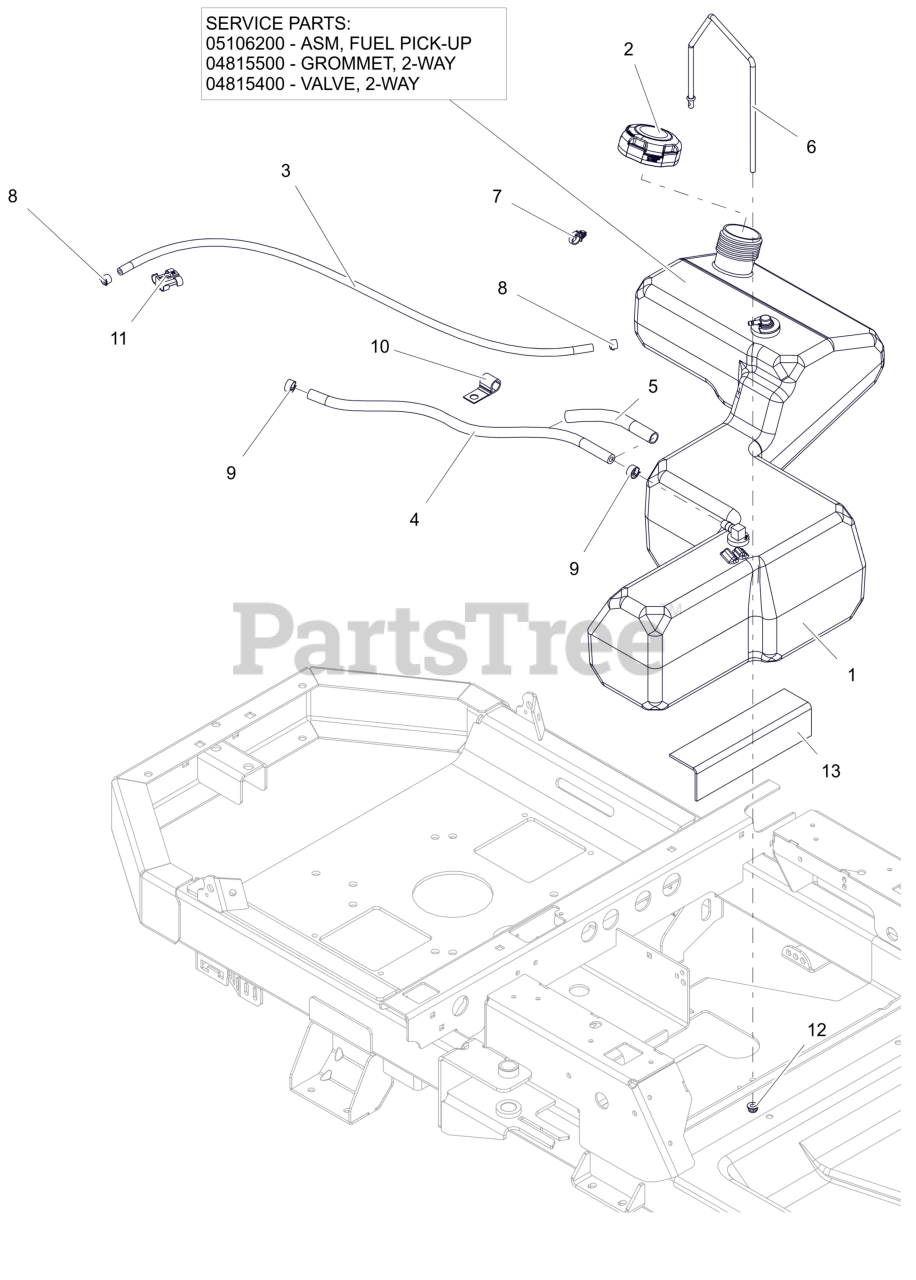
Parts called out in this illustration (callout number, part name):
1	ASM, FUEL TANK-IKON
1	ASM, IKON FUEL PICK-UP
1	GROMMET, 2-WAY
1	VALVE, 2-WAY
2	CAP-FUEL- 2.25 RATCHET INLET V
3	HOSE, .188 LOW-PERM BULK GAS
4	1 INCH OF HOSE, .25 LOW-PERM BULK GAS
5	SLEEVE, ANTI ABRASION .5" X .064" WALL
6	BRKT, FUEL
7	ROUTING CLIP (1/2" ID)
8	CLAMP-HOSE, SPRING .188
9	CLAMP, FUEL LINE
11	CLIP, T, .38-.50
12	NUT,NYL-FLG .25-20 GF ZCC
13	PAD, RUBBER-TANK
